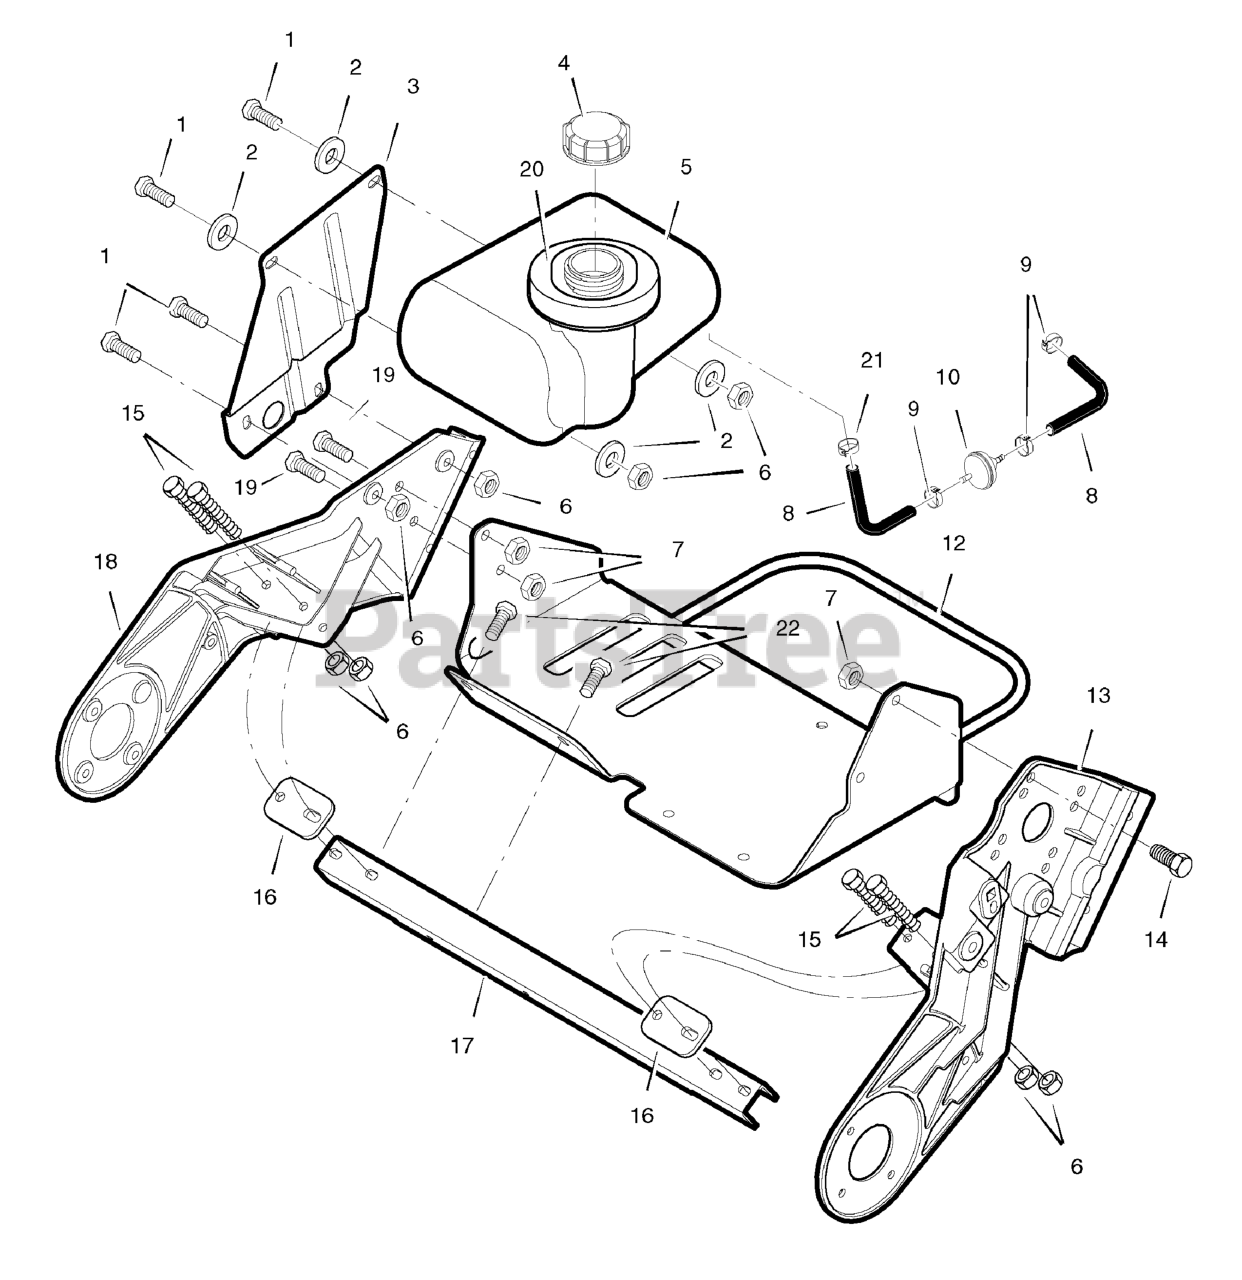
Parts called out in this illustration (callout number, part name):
1	SCREW, 1/4 - 20 x 3/4
2	WASHER
3	BRACKET, Fuel Tank
4	CAP, Fuel Tank
5	TANK, Fuel
6	NUT, Hex 1/4 - 20
7	NUT, Hex 5/16 - 18
8	HOSE, FUEL 12 INCHES
9	CLAMP, Fuel Line
10	FILTER, Fuel Line
12	CRADLE ASSEMBLY, Engine
13	FRAME, L.H.
14	SCREW, 5/16-18 x 5/8
15	SCREW, 1/4 - 20 x 2
16	PLATE, Mounting Support
17	SUPPORT, Frame
18	FRAME, R.H.
19	SCREW, 5/16-18 x 3/4
20	RING, Foam
21	CLAMP, Fuel Line
22	SCREW, 1/4 - 20 x 5/8
